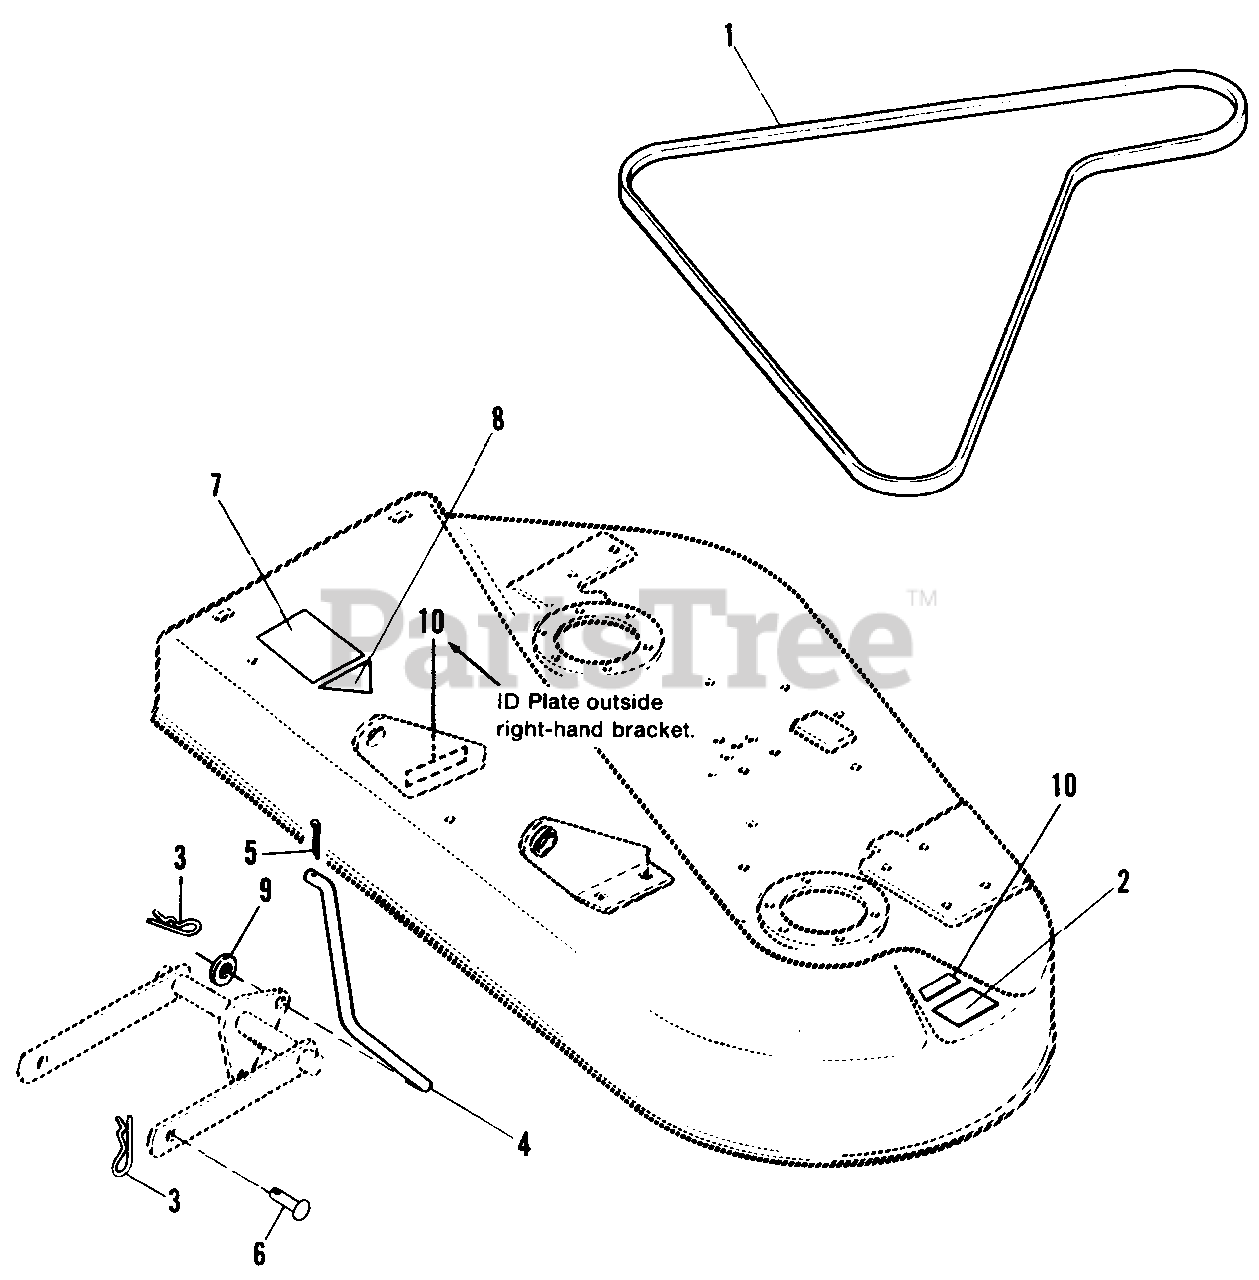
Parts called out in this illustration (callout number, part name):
1	V-BELT
2	DECAL, Danger
3	CLIP, Hairpin
4	ROD, Lift
5	PIN, 3/32 x 1
7	DECAL, Warning
8	DECAL, OPEI
9	WASHER, Plain, 3/8
10	PLATE, I.D.
